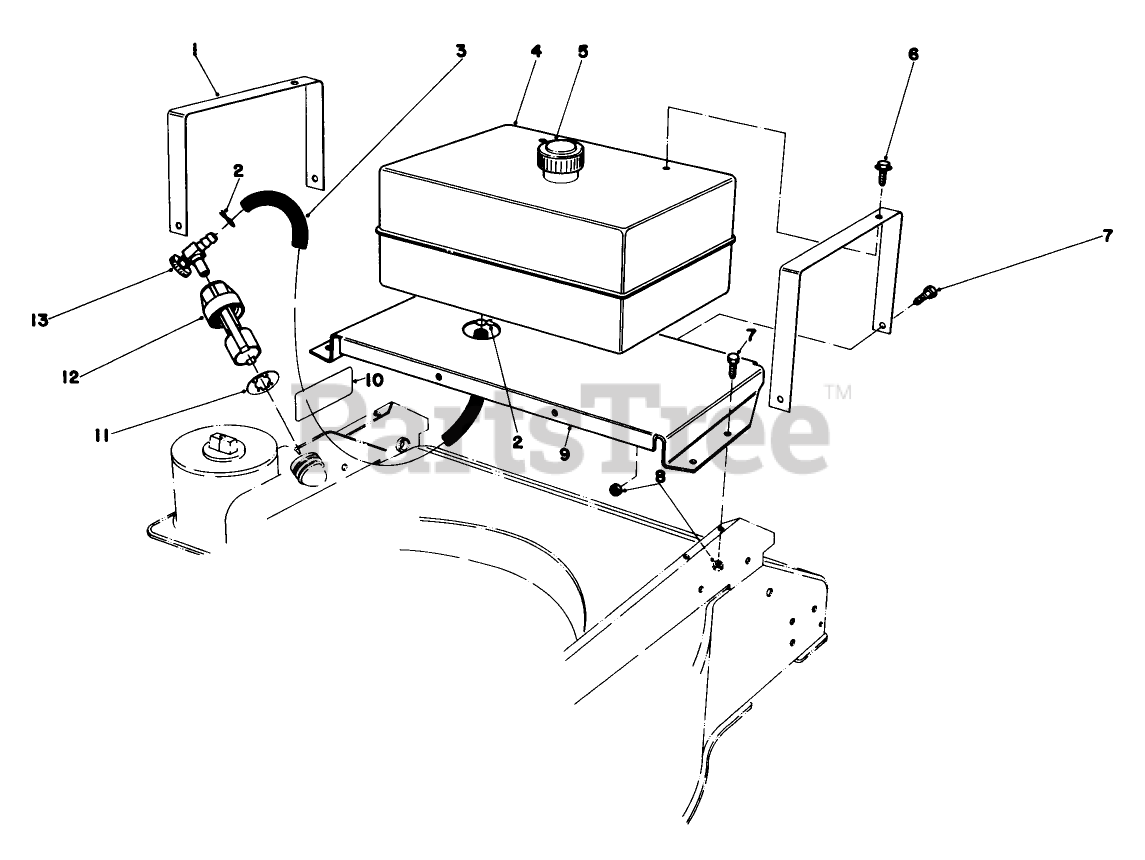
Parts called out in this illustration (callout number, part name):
6	SCREW-HWH
7	SCREW-HH
8	NUT-LOCK, CONE
12	FUEL CONT VALVE ASM
